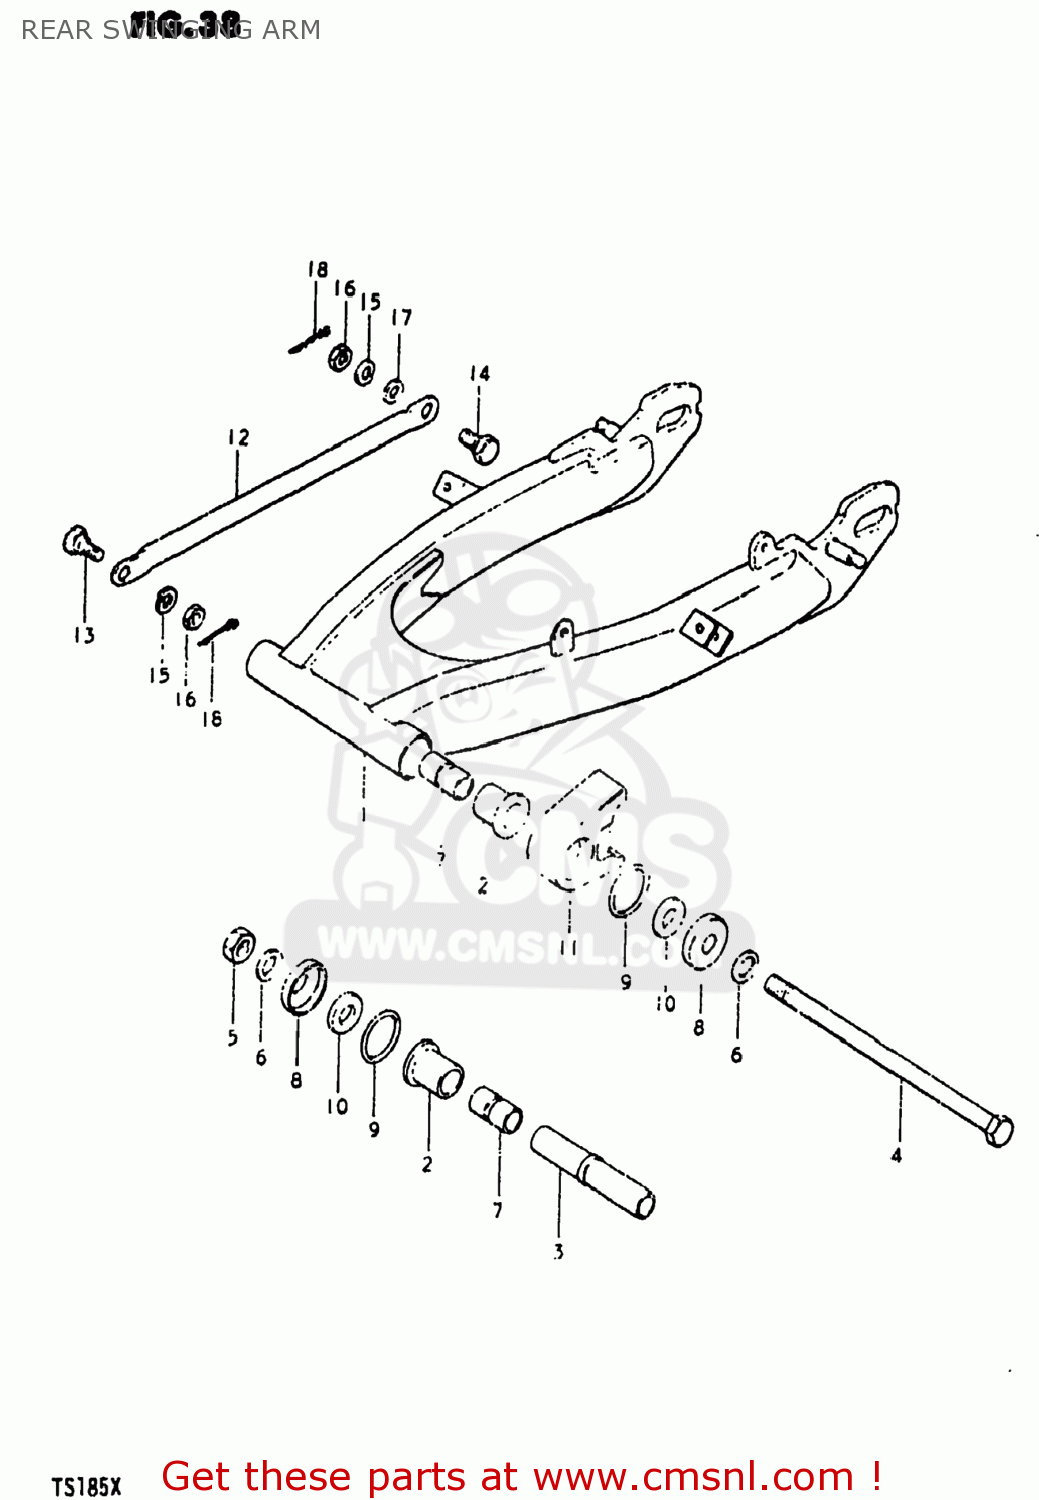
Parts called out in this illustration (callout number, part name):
1	SWING ARM ASSEMBLY,REAR
2	BUSH
3	SPACER,RR SWGARM PIVOT CTR
4	SHAFT,REAR SWING ARM
5	NUT 12MM
6	WASHER
7	SPACER,RR SWGARM PIVOT
8	COVER,SWGARM BUSH DUST SEAL
9	O RING(D:2,ID:24.5)
10	WASHER(12.5X24X2.3)
11	BUFFER,CHAIN TOUCH DEFENSE
12	TORQUE LINK,REAR
13	BOLT(8X22)
14	BOLT(8X26.5)
15	LOCK WASHER
16	NUT
17	WASHER
18	PIN
